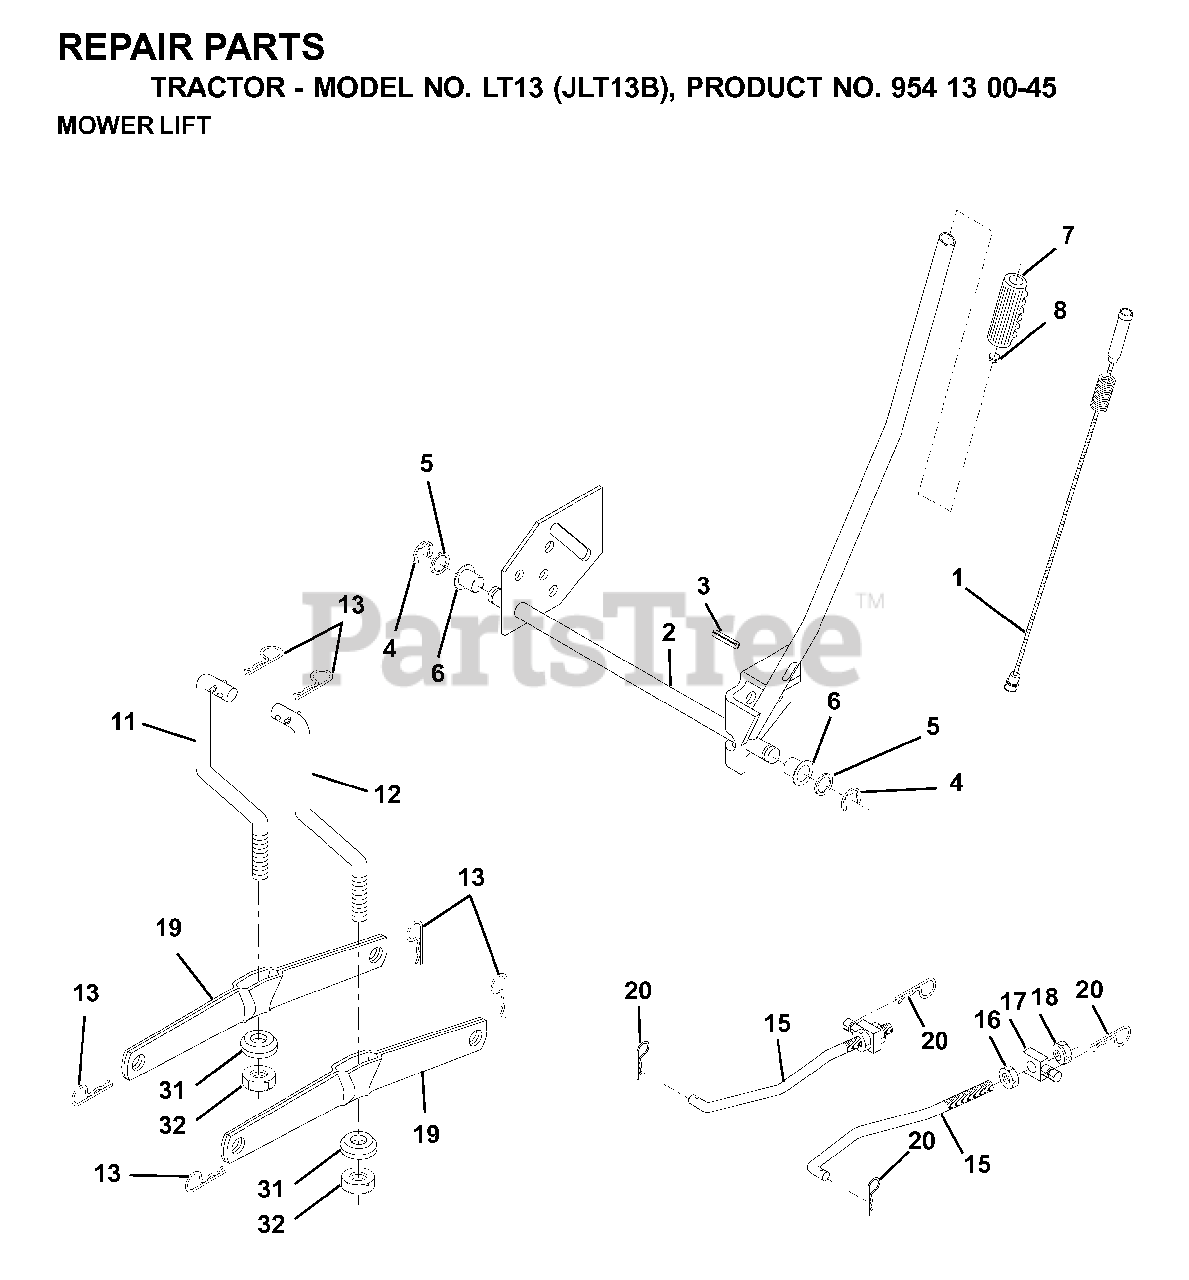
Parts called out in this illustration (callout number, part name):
1	WIRE ASM INNER W/ PLUNGER LT
2	SHAFT ASM R HANDLE
3	PIN GROOVE
4	RETAINING RING LT
6	BEARING.NYLON
7	GRIP
8	PLUNGER BUT KIT
11	LINK LIFT LH
12	LINK LIFT RH
13	RETAINER-SPRNG RB
15	LINK.SUSPENSION.FRONT
16	NUT
17	TRUNION
18	NUT
19	ARM.REAR.SUSPENSION
20	SPRING RETAINER
31	BEARING.PIVOT.LIFT
32	NUT CROWNLOCK 3/8-24
